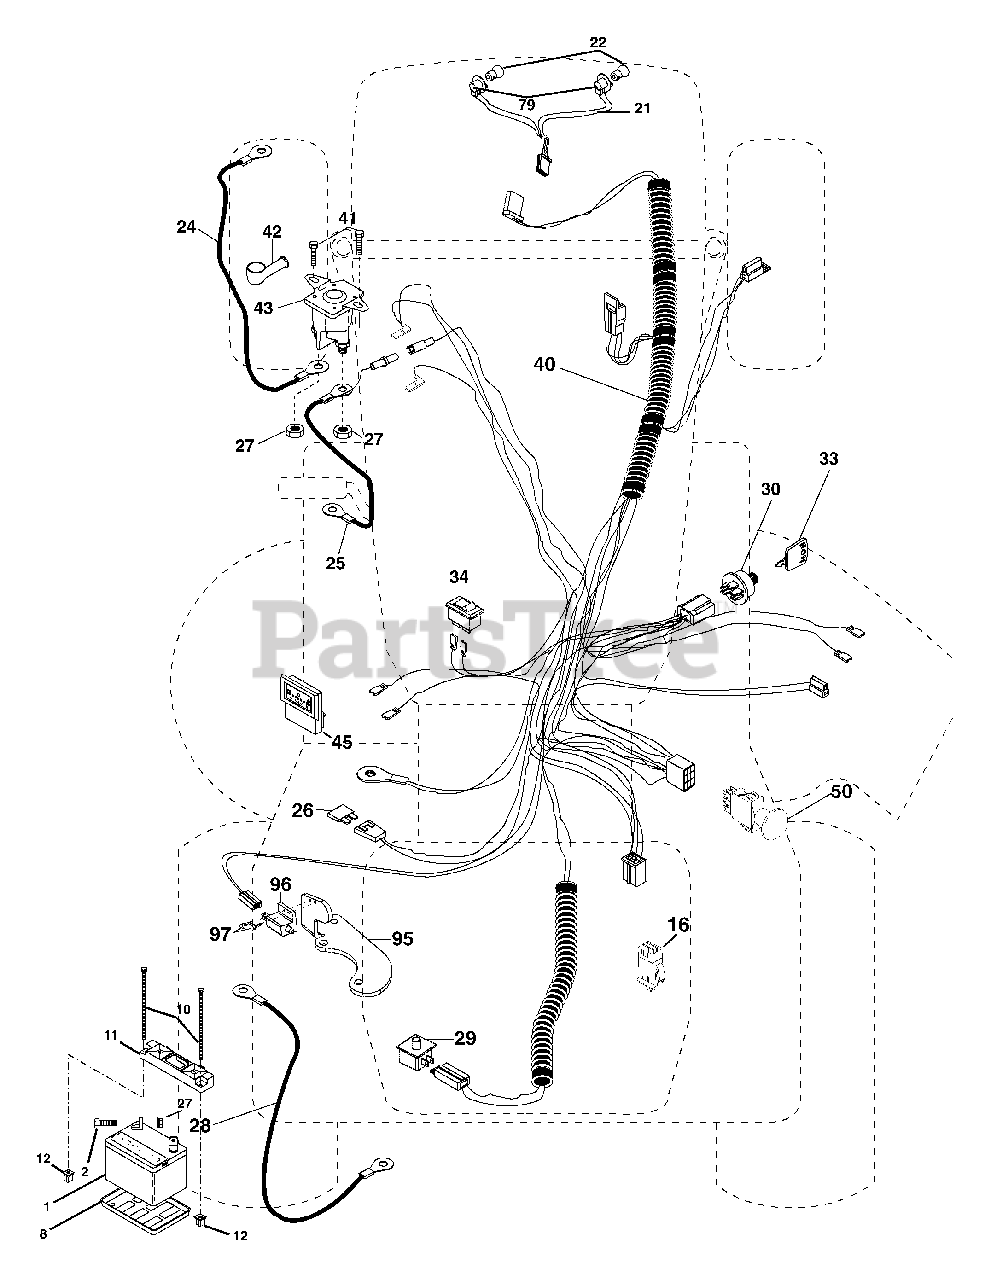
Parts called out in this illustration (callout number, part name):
1	Battery
2	Bolt Hex Head 1/4-20 x 3/4
8	Tray, Battery
10	Bolt 1/4-20 x 7.5 Zinc
11	Hold down Battery Dash Mount
12	Nut Push Nylon 1/4"
16	Switch Interlock
21	Harness Socket Light W/4152J
22	Bulb Light
24	Cable Battery
25	Cable Battery
26	Fuse
27	Nut Keps Hex 1/4-20 Unc
28	Cable, Ground
29	Switch, Seat
30	Switch, Ign
33	Key, Ignition
34	Switch Light/Reset
40	Harness Ign.
41	Screw Thd Cut 1/4-20 x 1/2
42	Cover, Terminal
43	Solenoid
45	Ammeter
50	Switch, PTO
79	Socket Asm. Bulb
95	Bracket ROS
96	Switch Intek
97	Screw #10-32 5 3/8
